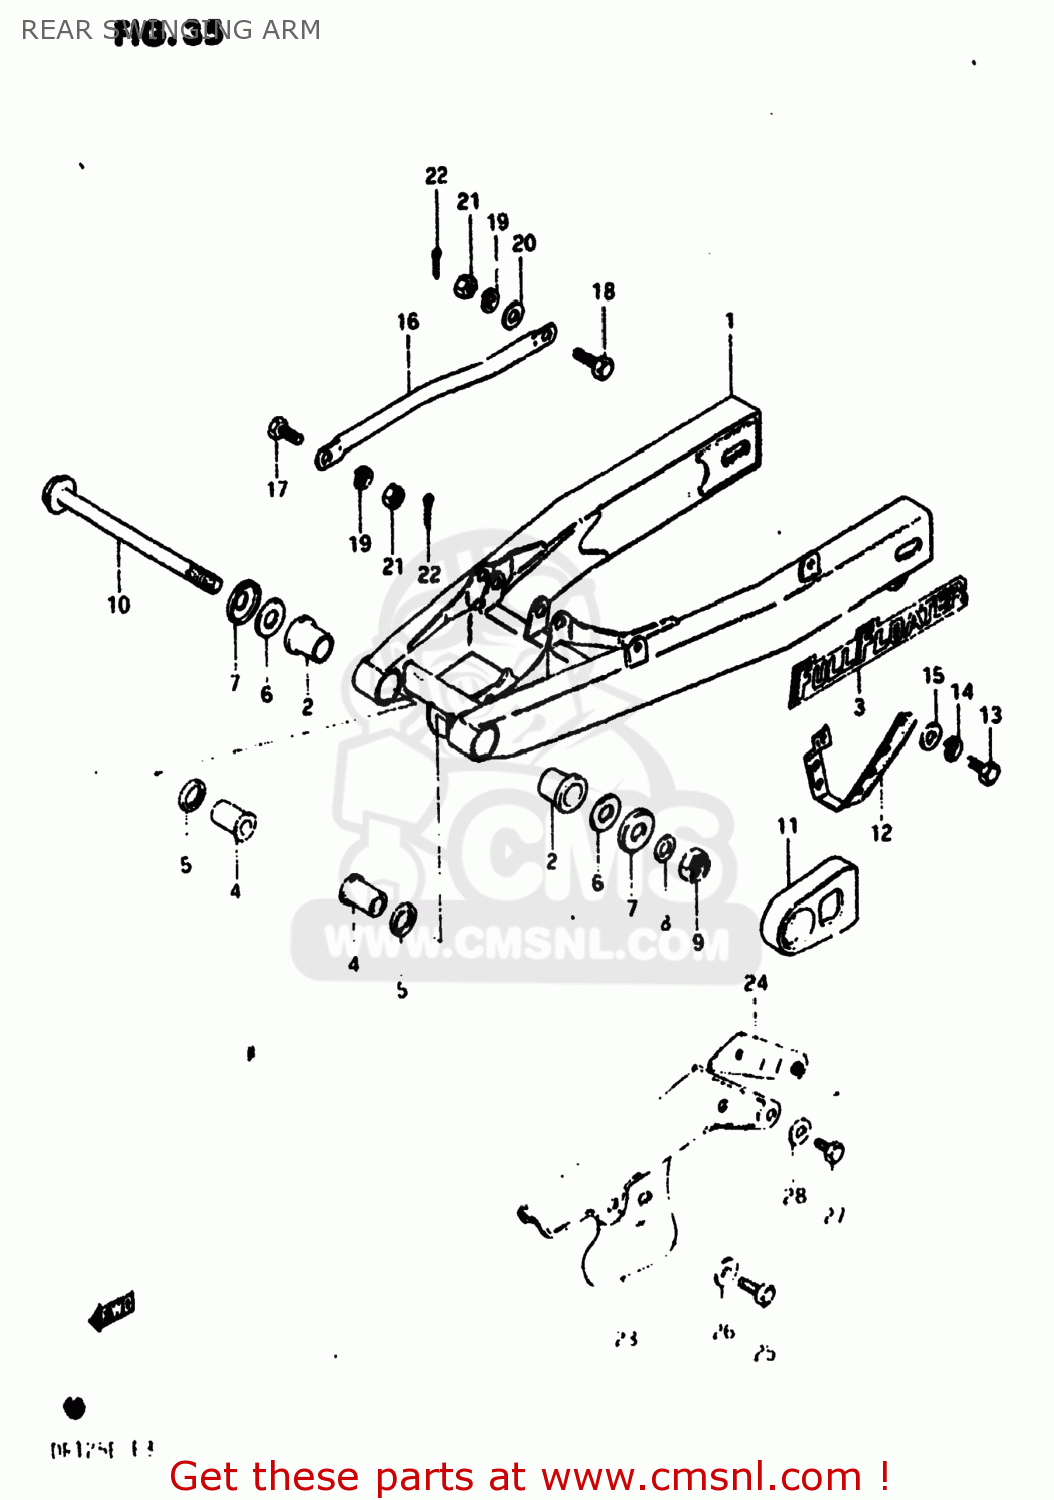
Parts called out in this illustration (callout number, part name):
1	SWING ARM ASSEMBLY,REAR
2	BUSHING,REAR SWING ARM PIVOT
3	EMBLEM,REAR SWING ARM
4	SPACER,RR SWGARM PIVOT
5	SEAL,OIL(20X27X5)
6	WASHER
7	CVR,RR SWGARM DUST SEAL(OD:40)
8	WASHER
9	NUT 14MM
10	SHAFT,REAR SWING ARM
11	BUFFER,CHAIN TOUCH DEFENSE
12	GUIDE,CHAIN
13	BOLT 8X12
14	LOCK WASHER
15	WASHER
16	TORQUE LINK,REAR
17	BOLT(8X22)
18	BOLT(8X26.5)
19	LOCK WASHER
20	WASHER
21	NUT
22	PIN 20X20
23	CASE,CHAIN
24	REINFORCEMENT,CHAIN CASE
25	BOLT(6X8)
26	WASHER
27	BOLT, UPPER
28	WASHER
